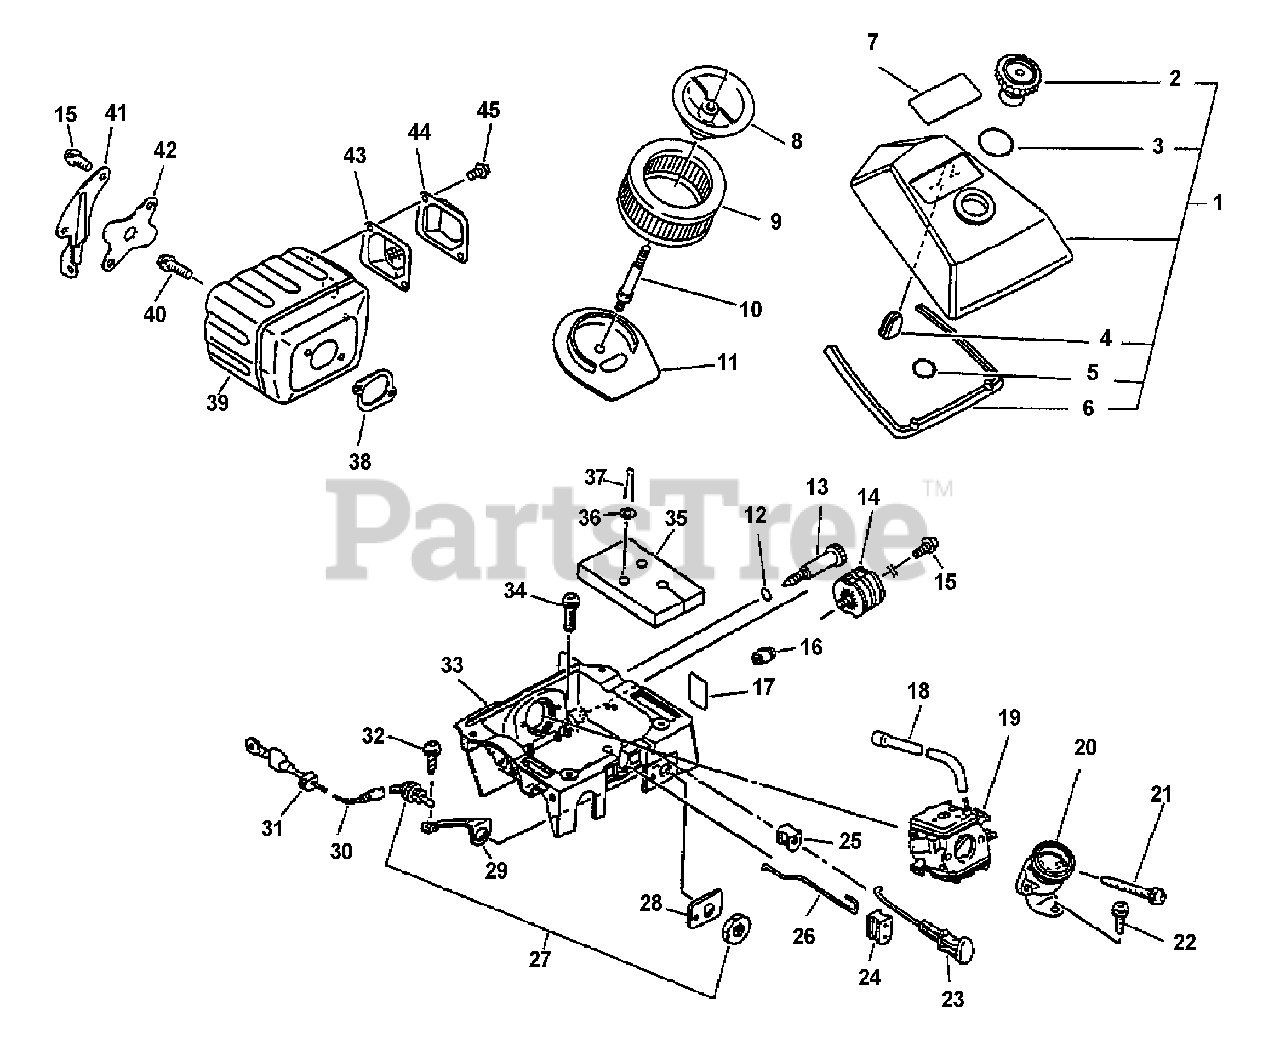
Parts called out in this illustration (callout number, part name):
1	COVER ASSY, AIR FILTER
2	THUMBSCREW
3	O-RING -21
5	O-RING P-11
6	GASKET, AIR FILTER
7	LABEL, CS-6700
8	BRACKET, AIR FILTER
9	FILTER ASSY, AIR
10	STUD
11	BRACKET, AIR FILTER
12	O-RING 7 MM
13	SCREW, IDLE ADJUST - GRAY
15	BOLT 5×14
17	LABEL, CAUTION - IDLE
18	PIPE, IMPULSE
19	CARBURETOR - HDA-151A
20	ADAPTOR, INTAKE
21	SCREW 5×53
22	SCREW 5×14
23	ROD, CHOKE
24	GROMMET, THROTTLE ROD
25	GROMMET
26	ROD, THROTTLE
27	SWITCH, ON-OFF
28	LABEL, STOP
29	PLATE, GROUND
30	LEAD
32	SCREW 4×10
33	CASE, CARBURETOR
34	BOLT 5×20
35	GASKET, CARBURETOR CASE
37	PIN, COTTER 3×18
38	GASKET, EXHAUST
39	MUFFLER
40	BOLT 5×20
41	BRACKET, MUFFLER
42	COVER, MUFFLER
43	SCREEN, SPARK ARRESTER
44	OUTLET, EXHAUST
45	BOLT 4×10
